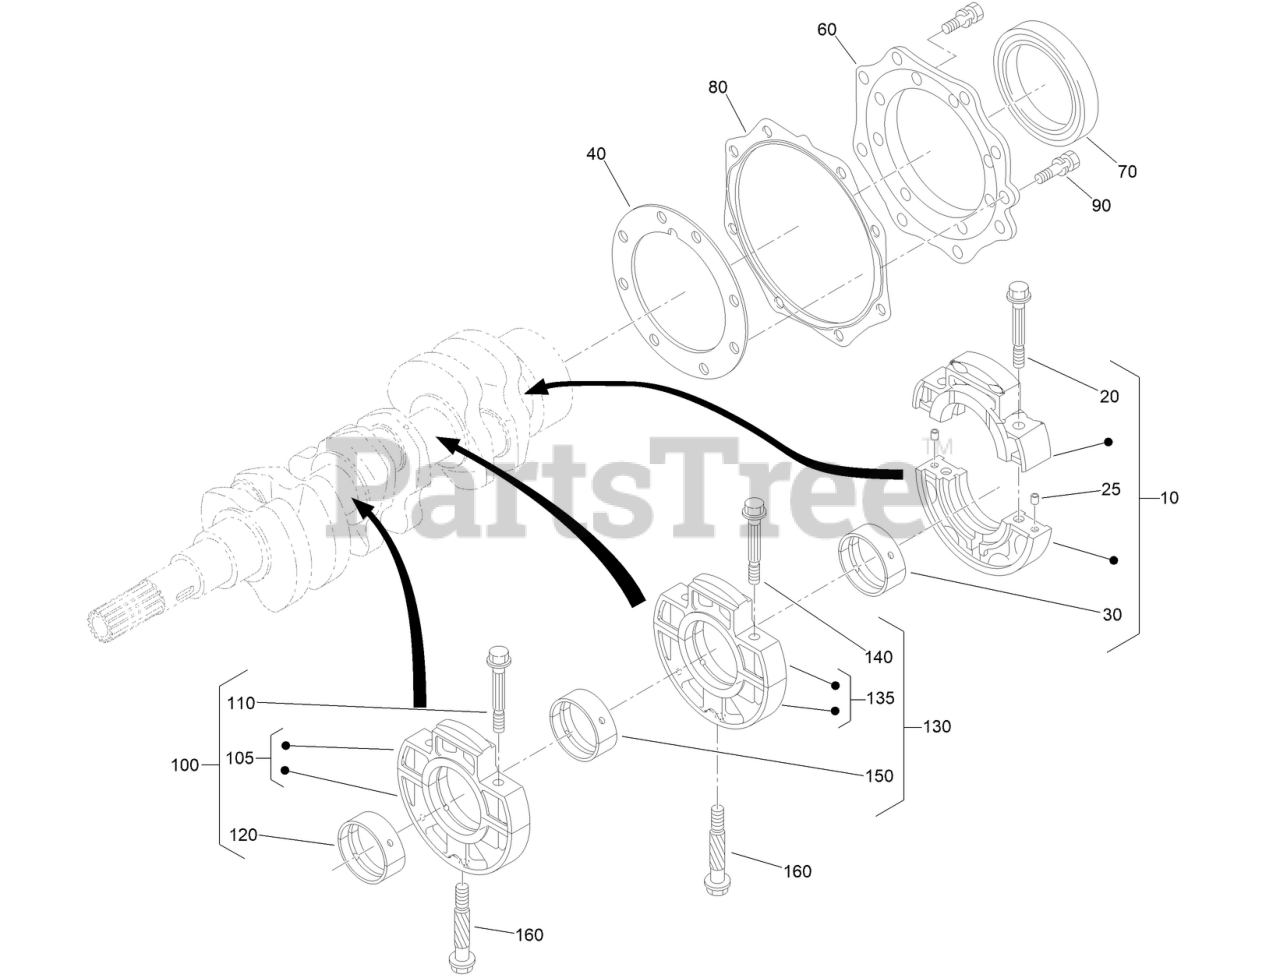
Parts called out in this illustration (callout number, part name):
10	WHEEL BEARING CASE ASM
20	BOLT-FLANGE
25	PIN-STRAIGHT
30	CRANKSHAFT-METAL (STD SET)
30	METAL,CRANKSHAFT
30	METAL-CRANKSHAFT
40	GASKET-CASE, BEARING
60	COVER-CASE, BEARING
70	SEAL-OIL
80	GASKET-COVER, CASE
100	BEARING CASE ASM
105	MAIN BEARING CASE ASM
110	BOLT-CASE, BEARING
120	CRANKSHAFT-METAL (STD SET)
120	CRANKSHAFT-METAL (-0.2MM SET)
120	METAL-CRANKSHAFT
130	BEARING CASE ASM
135	MAIN BEARING CASE ASM
140	BOLT-CASE, BEARING
150	CRANKSHAFT-METAL (STD SET)
150	CRANKSHAFT-METAL (-0.2MM SET)
150	METAL-CRANKSHAFT
160	BOLT-CASE, BEARING
